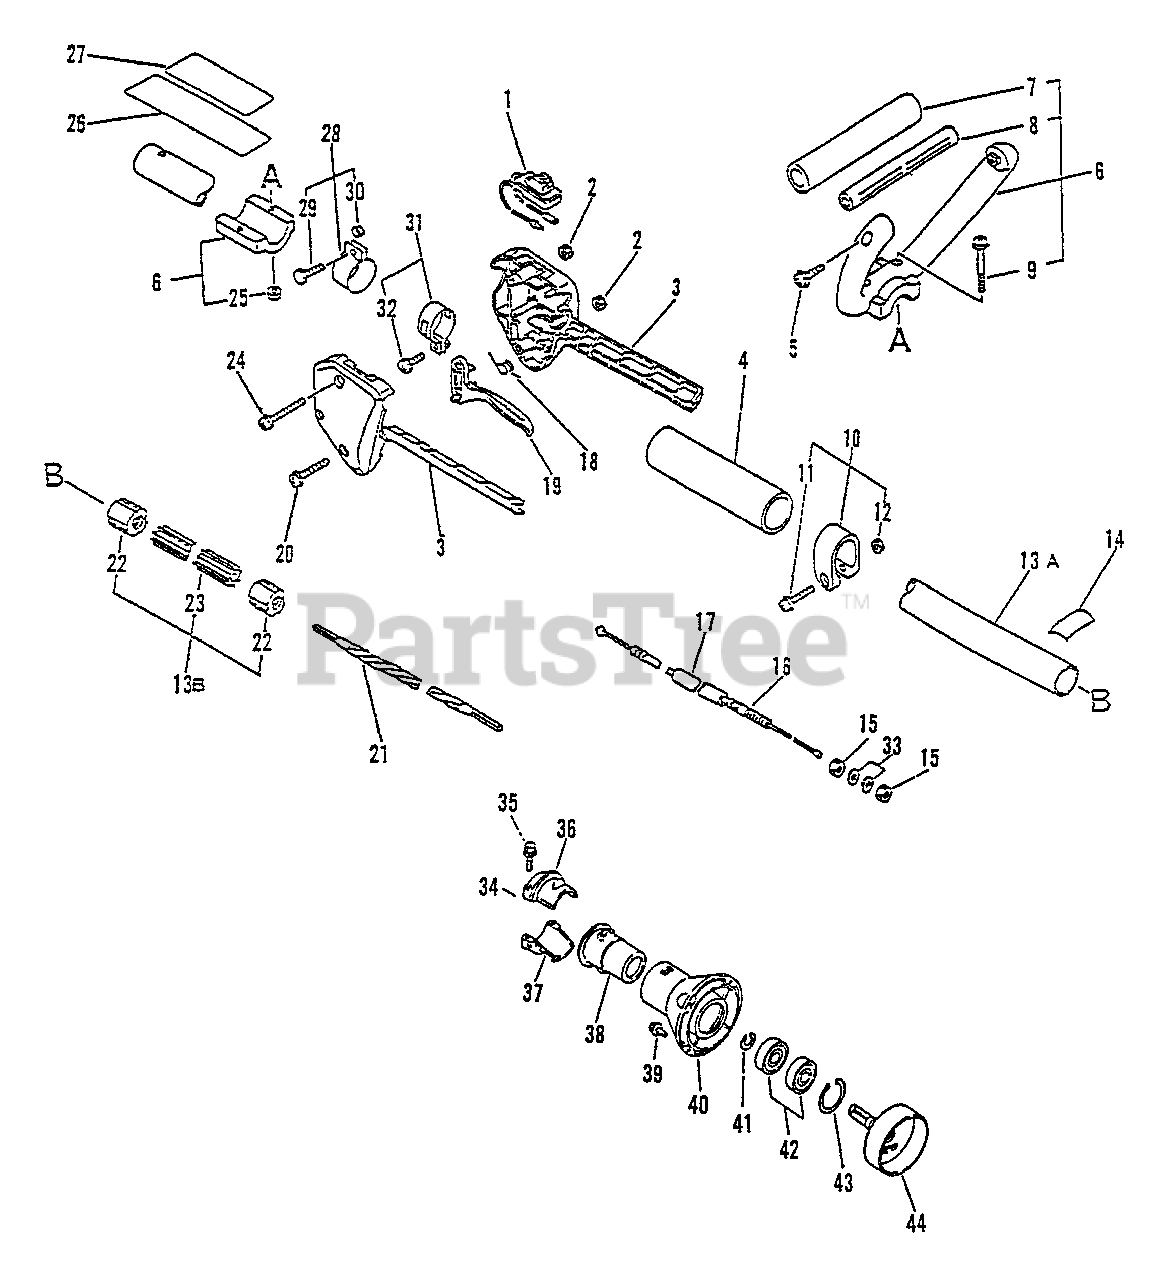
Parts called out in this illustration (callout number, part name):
1	IGNITION SWITCH ASSY
3	CONTROL HANDLE KIT
4	GRIP, HANDLE
5	SCREW - 5X30
6	LOOP HANDLE ASSY
7	GRIP, HANDLE
9	SCREW - 6X35
10	CLAMP KIT
11	SCREW - 5X30
13	MAIN PIPE ASSY
13A	MAIN PIPE ASSY
13B	MAIN PIPE ASSY
14	LABEL - ALIGNMENT
16	CABLE, THROTTLE
17	TUBE - VINYL
18	SPRING, TRIGGER
19	TRIGGER, THROTTLE
20	SCREW - 5X25
21	DRIVESHAFT - FLEXIBLE
23	LINER - FLEXIBLE
24	SCREW - 5X35
25	LOCKNUT - 6
26	LABEL - CAUTION
27	LABEL - CAUTION
28	CLAMP
29	BOLT - 5X18
31	CLAMP KIT
32	SCREW - 5X14
33	WASHER - 6
34	HOLDER KIT
35	BOLT - 5X25
36	CLAMP, MAIN PIPE - UPPER
37	CLAMP, MAIN PIPE
39	SCREW - 5X16
40	CASE, CLUTCH - GRAY
41	RING, RETAINING - 12
42	BEARING, BALL - 6001
43	RING, RETAINING - 28
44	DRUM, CLUTCH
